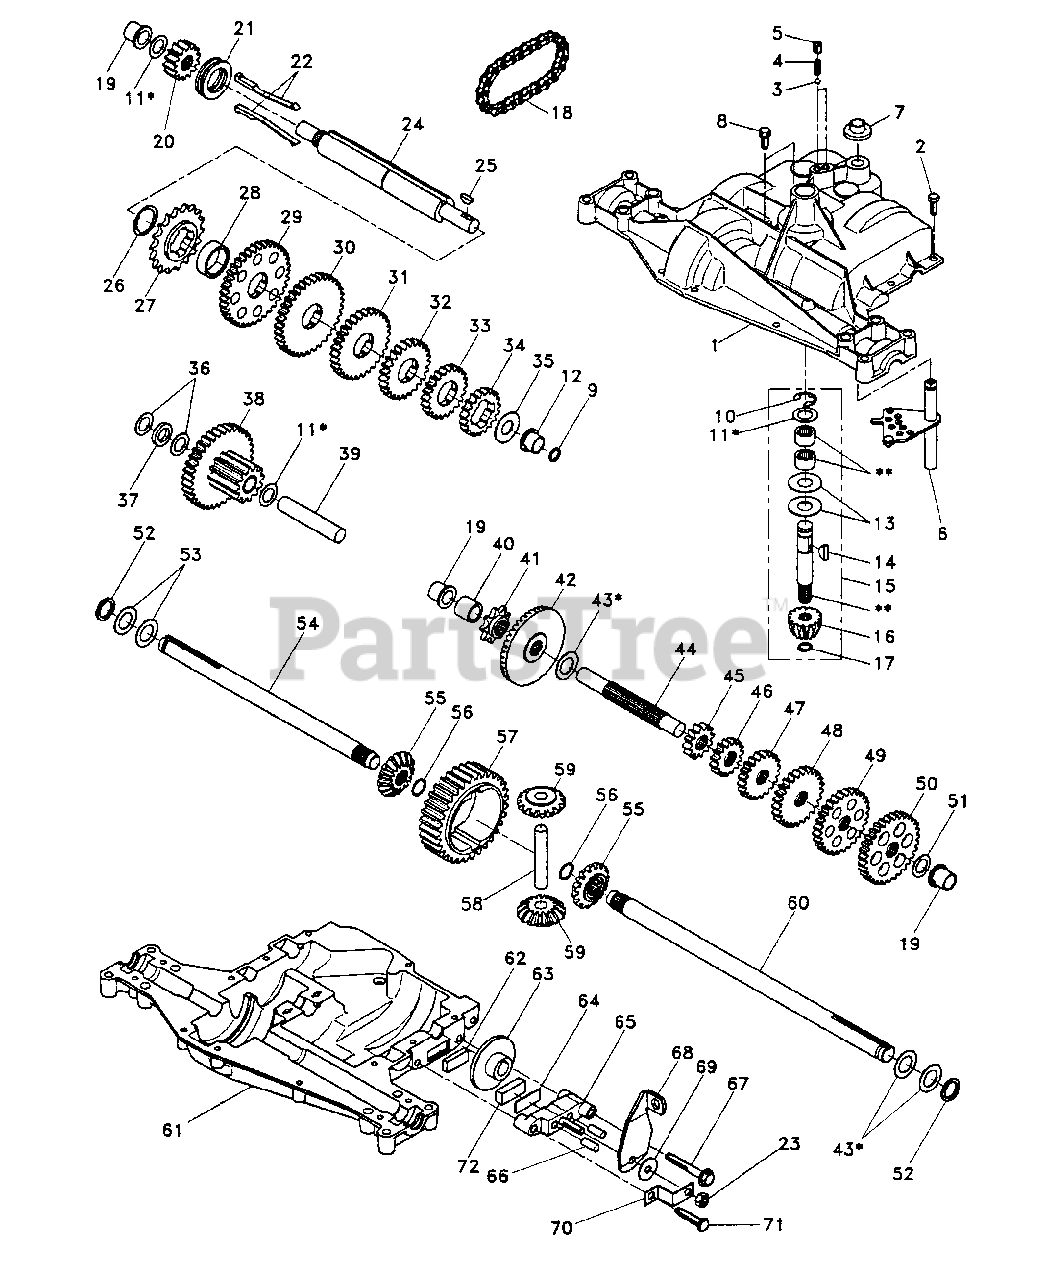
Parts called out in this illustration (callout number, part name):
1	Housing, Upper
2	Screw, Self-Tapping, Large 1/4-20 x .734
3	Ball, Detent
4	Spring, Detent
5	Screw, Set
6	Kit, Shifter Assembly
7	Boot, Shifter
8	Screw, Self-Tapping, with Sealer
9	Square Ring
10	Ring, Retaining
11	Assembly, Kit, Shim .625 Shaft
12	Bearing, Flange
13	Washer, Plain .632 x 1.38 x .046
14	Key, Woodruff, #9
15	Assembly, Kit, Input Shaft
16	Pinion, Bevel, 14 Teeth
17	Ring, Retaining
18	Chain, 24 Pitches
19	Bearing, Flange
20	Gear, Spur, 14 Teeth
21	Collar, Clutch
22	Assembly, Kit, Clutch Keys
23	Locknut 5/16-24
24	Shaft, Intermediate
25	Key, Woodruff, #61
26	Ring, Retaining
27	Sprocket, 18 Teeth (Reverse)
29	Gear, Spur, 37 Teeth (1 st)
30	Gear, Spur, 35 Teeth (2 nd)
31	Gear, Spur, 30 Teeth (3 rd)
32	Gear, Spur, 25 Teeth (4 th)
33	Gear, Spur, 22 Teeth (5 th)
34	Gear, Spur, 19 Teeth (6 th)
35	Washer, Plain .640 x 1.37 x .061
36	Washer, Plain .632 x 1.00 x .026
37	Spacer .630 x 1.00 x .169
38	Assembly, Gear, Combination of 12 Teeth and 35 Teeth
39	Shaft, Idler
40	Spacer .635 x .875 x .755
41	Sprocket, 9 Teeth (Reverse)
42	Gear, Bevel, 42 Teeth
43	Assembly, Kit, Shim .750 Shaft
44	Shaft, Drive
45	Gear, Spur, 12 Teeth (1 st)
46	Gear, Spur, 15 Teeth (2 nd)
47	Gear, Spur, 20 Teeth (3 rd)
48	Gear, Spur, 25 Teeth (4 th)
49	Gear, Spur, 28 Teeth (5 th)
50	Gear, Spur, 31 Teeth (6 th)
51	Washer, Plain .632 x 1.00 x .060
52	Washer, Neoprene
53	Washer, Plain .758 x 1.25 x .031
54	Axle, L.H.
55	Gear, Miter, 15 Teeth
56	Ring, Retaining
57	Gear, Spur, 32 Teeth
58	Shaft, Cross
59	Gear, Miter, 15 Teeth
60	Axle, R.H.
61	Housing, Lower
62	Puck, Friction
63	Disc, Brake
65	Jaw, Brake
66	Pin, Dowel
67	Screw, Self-Tapping, Large 5/16-18 x 2.25
68	Lever, Actuating
69	Washer, Plain .321 x 1.00 x .055
70	Bracket, Anti-Rotation
71	Screw, Self-Tapping, Large 5/16-18 x 1.44
72	Puck, Friction
73	Grease
